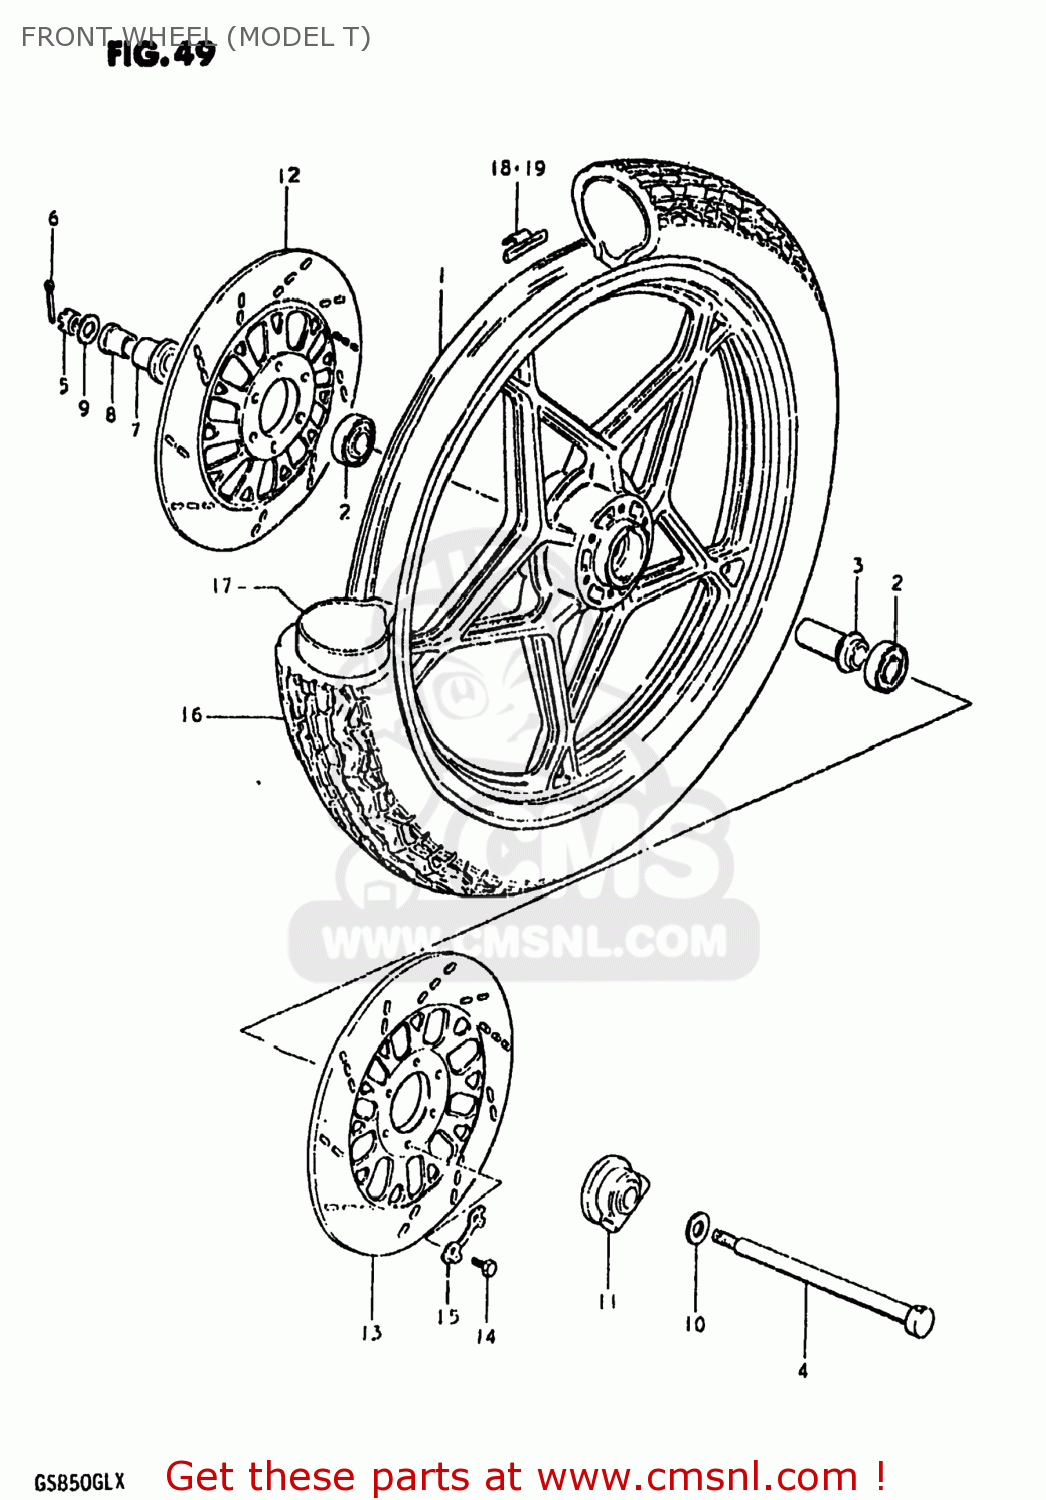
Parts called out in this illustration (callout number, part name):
1	CASTING WHEEL,FRONT
2	BEARING
3	SPACER,FR HUB BEARING
4	AXLE,FR
5	NUT 12MM
6	COTTER PIN
7	SPACER,FR AXLE,R
8	SPACER
9	WASHER
10	WASHER(15.5X26X2.3)
11	BOX ASSY,SPEEDOMETER GEAR
12	DISC,FR BRAKE,R
13	DISC,FR BRAKE,L
14	BOLT(8X25)
15	WASHER
16	TIRE,FRONT
17	TUBE,INNER
18	BALANCER,WHEEL
19	BALANCER,WHEEL
